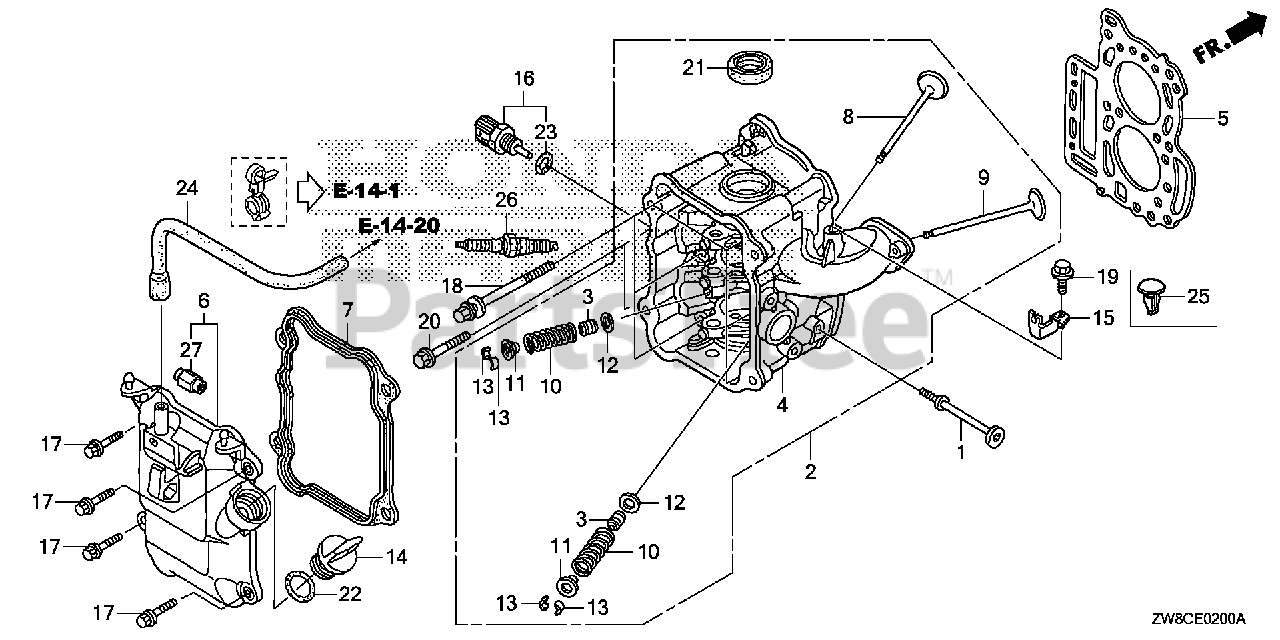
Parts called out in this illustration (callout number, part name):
1	STOPPER, ENGINE SIDE
3	SEAL, VALVE STEM (NOK)
4	CYLINDER HEAD *NH8* (DARK GRAY)
5	GASKET, CYLINDER HEAD
6	COVER, HEAD
7	GASKET, HEAD COVER
8	VALVE, IN.
9	VALVE, EX.
10	SPRING, VALVE
11	RETAINER, VALVE SPRING
12	SEAT, VALVE SPRING
13	COTTER, VALVE
14	CAP, OIL (YELLOW)
15	HOLDER, CABLE
16	SENSOR ASSY., WATER TEMPERATURE
17	BOLT, FLANGE (6X22)
18	BOLT, FLANGE (8X83)
19	BOLT, FLANGE (6X14) (CT200)
20	BOLT, FLANGE (8X40)
21	OIL SEAL (20X32X6)
22	O-RING (26X2.7)
23	O-RING (9.5X1.5) (HONDA KIKAKI)
24	TUBE, BREATHER
26	SPARK PLUG (CR5EH-9)
26	SPARK PLUG (U16FER9)
27	NUT, INSERT
